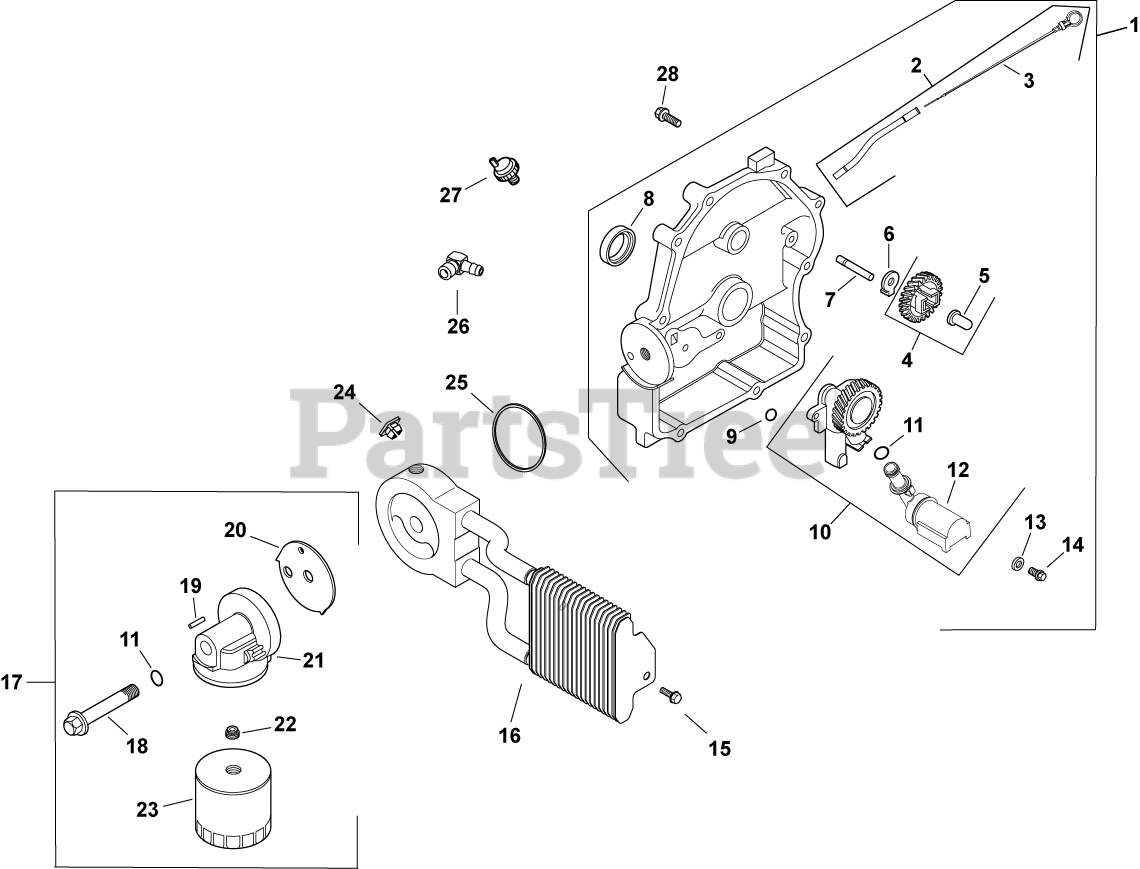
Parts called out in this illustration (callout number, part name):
1	CLOSURE PLATE ASSEMBLY USE 24 009 237-S
2	KIT, DIPSTICK/DIPSTICK TUBES
4	KIT, GOVERNOR GEAR W/PIN
5	PIN, GOVERNOR REGULATING
6	TAB, LOCKING
7	SHAFT, GOVERNOR GEAR
8	SEAL, OIL
10	PUMP ASSEMBLY, OIL-USE 24 393 53-S
11	O-RING, OIL PICK-UP
12	PICK-UP, OIL
13	WASHER, FLAT 6 MM
14	SCREW,FLG THD FRM M6X1.0X25-(#25086395S)
15	SCREW, TAP M6X1.7X18
16	KIT, OIL COOLER - DISCONTINUED
17	KIT, OIL FILTER BASE(ROT)
18	BOLT, OIL FILTER ADAPTER
19	PIN, ROLL
20	GASKET, OIL FILTER ADAPTER USE 24 041 88-S
21	ADAPTER, OIL FILTER-USE 24 029 77-S
22	NIPPLE, OIL FILTER
23	OIL FILTER
24	NUT, PLASTIC (KM)-USE 25 100 37-S
26	CONNECTOR, 90 DEG. HOSE
27	SENSOR, OIL PSI
28	SCREW, FLG M8X1.25X45
